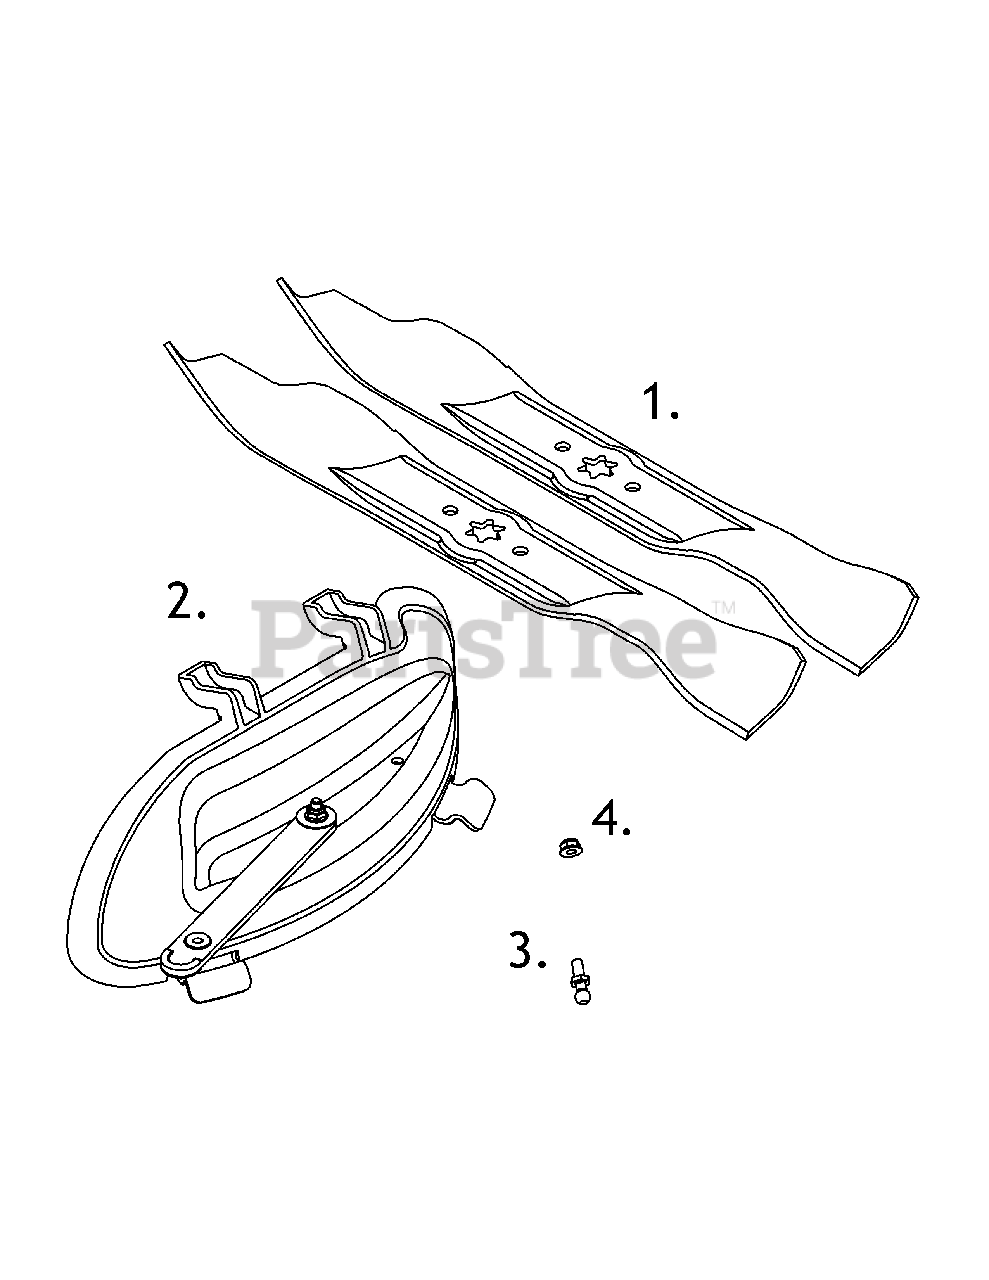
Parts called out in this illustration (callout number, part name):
1	Mulching Blades 21.23"
2	42" Deck Mulch Plug
3	Grass-catcher Pin, 1/4-20
4	Flange Lock Nut, 1/4-20
